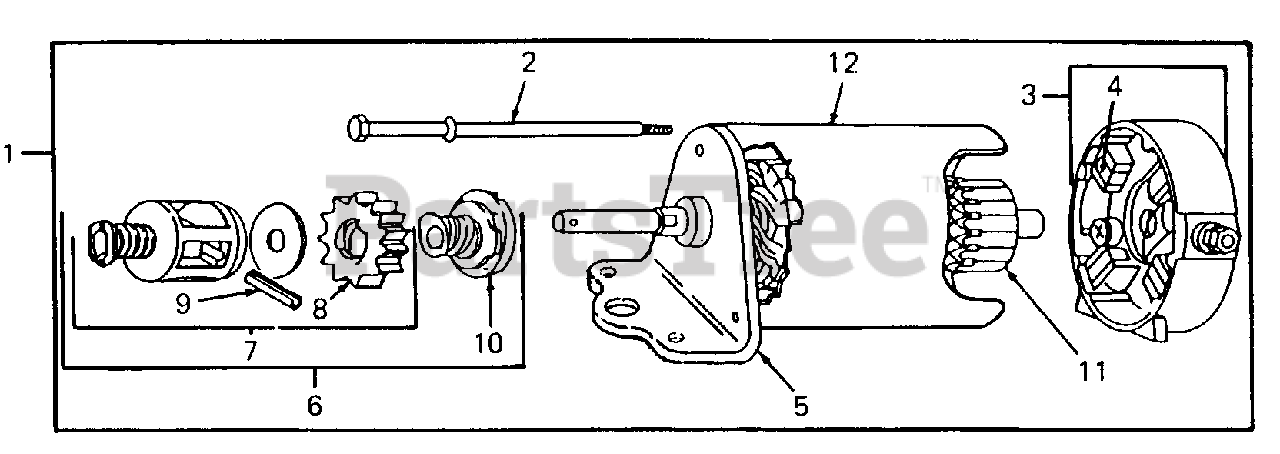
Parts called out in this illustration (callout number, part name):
1	Motor, Starting
2	Bolt, Hex
3	End Cap Assy
4	Brush Assy
5	Cap Assy, Drive End
6	Drive Assy
7	Retainer & Pin
8	Gear
9	Pin, Roll
10	Clutch Assy
11	Armature Assy
12	Housing Assy
